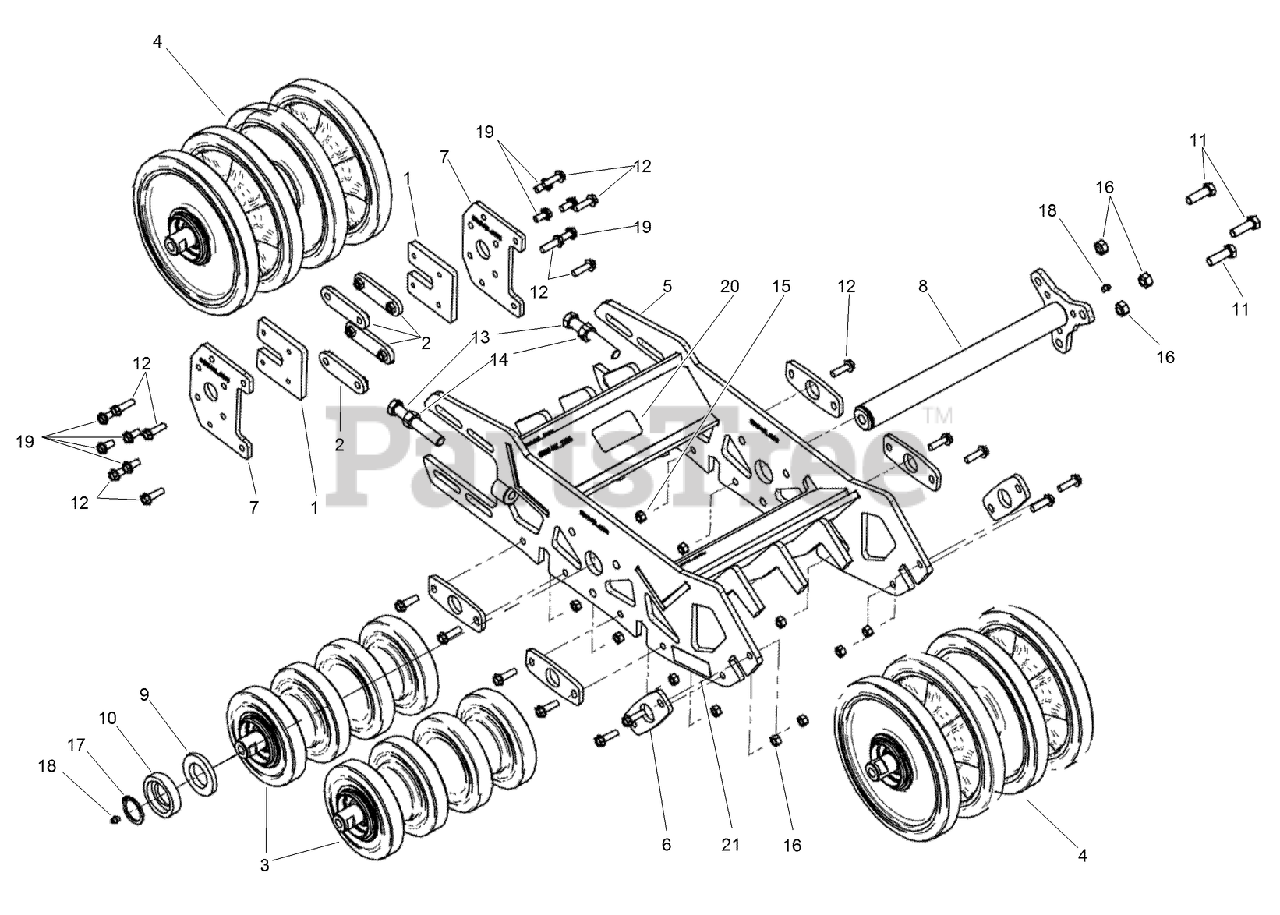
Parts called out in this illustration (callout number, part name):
1	TENSIONER-INNER, 19.5 IN TRACK
2	TENSIONER-CLAMPING, 19.5 IN TRACK
3	ASSEMBLY - Axle for 19.50 Track, 3 Wheels 8.00 Dia
4	ASSEMBLY - Axle for 19.50 Track, 3 Wheels 13.50 Dia
5	ASSEMBLY - Track Beam
6	PLATE - Axle Retaining
7	PLATE - Tensioner Outer
8	PIVOT AXLE
9	SPACER - Axle Pivot
10	SPACER
11	SCREW-FLANGE
13	BOLT - Hex Hd FT M20 - 2.5 x 130 mm
14	NUT - Hex M20-2.5
15	NUT-HHF, LOCK
16	NUT-HHF
17	RING - Retaining
18	FITTING-Lube 1/8-27 Dryseal PTF
19	SCREW-HHF
20	LABEL - Danger
21	NAMEPLATE
